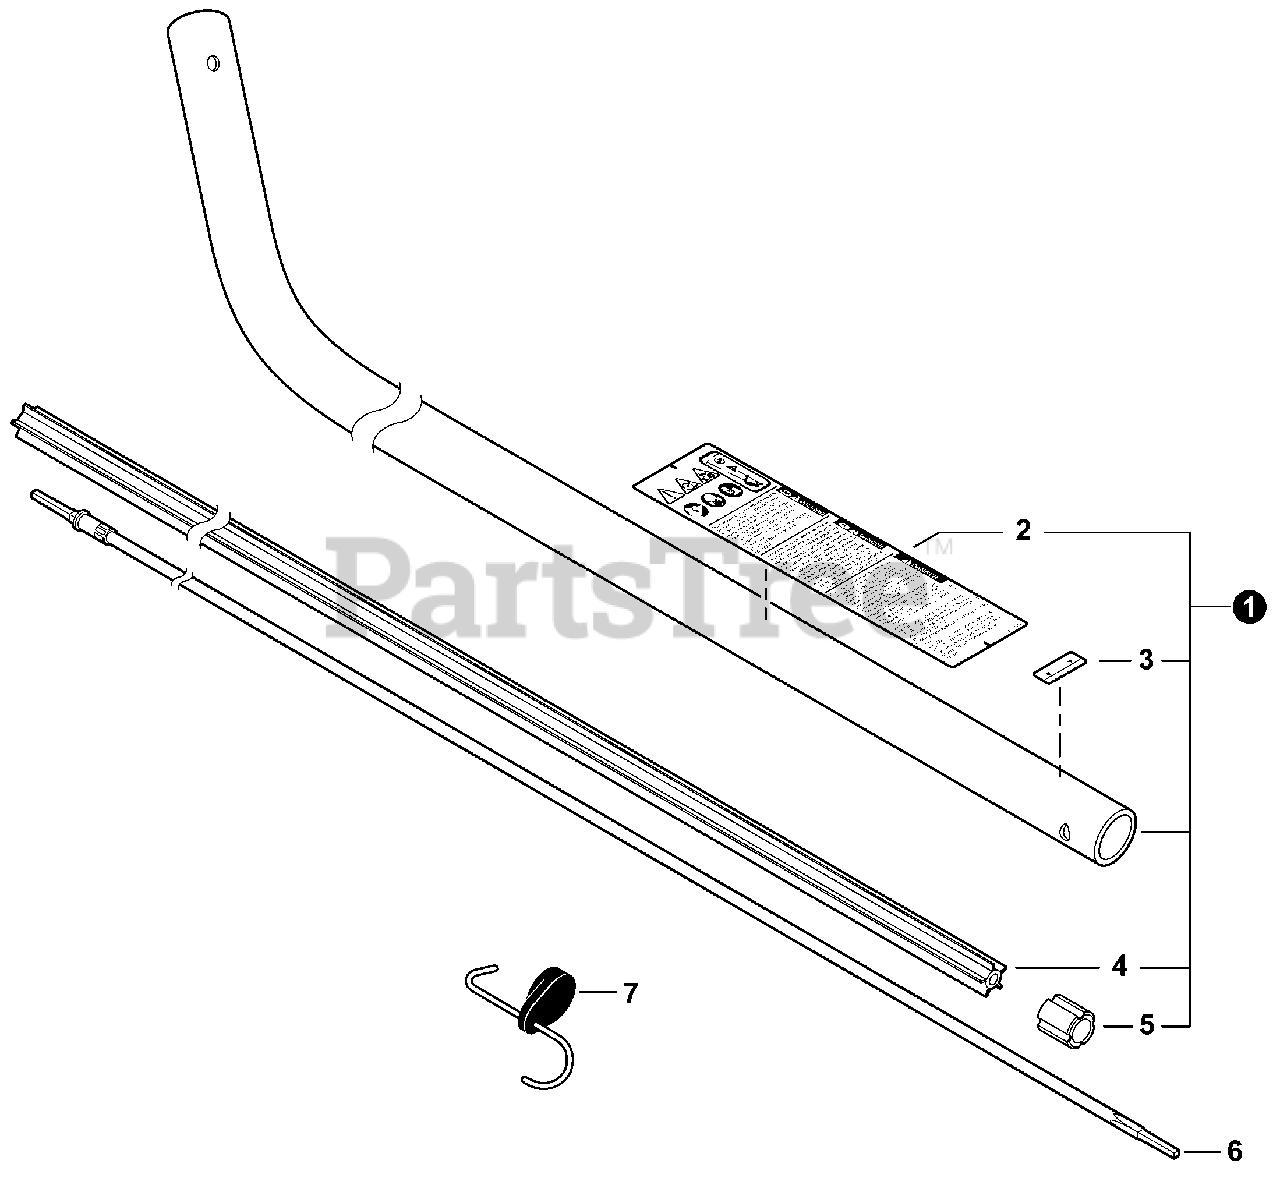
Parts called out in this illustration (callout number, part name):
1	MAIN PIPE ASSY
2	LABEL, CAUTION
3	LABEL - ALIGNMENT
4	LINER - FLEXIBLE
6	DRIVESHAFT - FLEXIBLE
7	HANGER, ATTACHMENT
